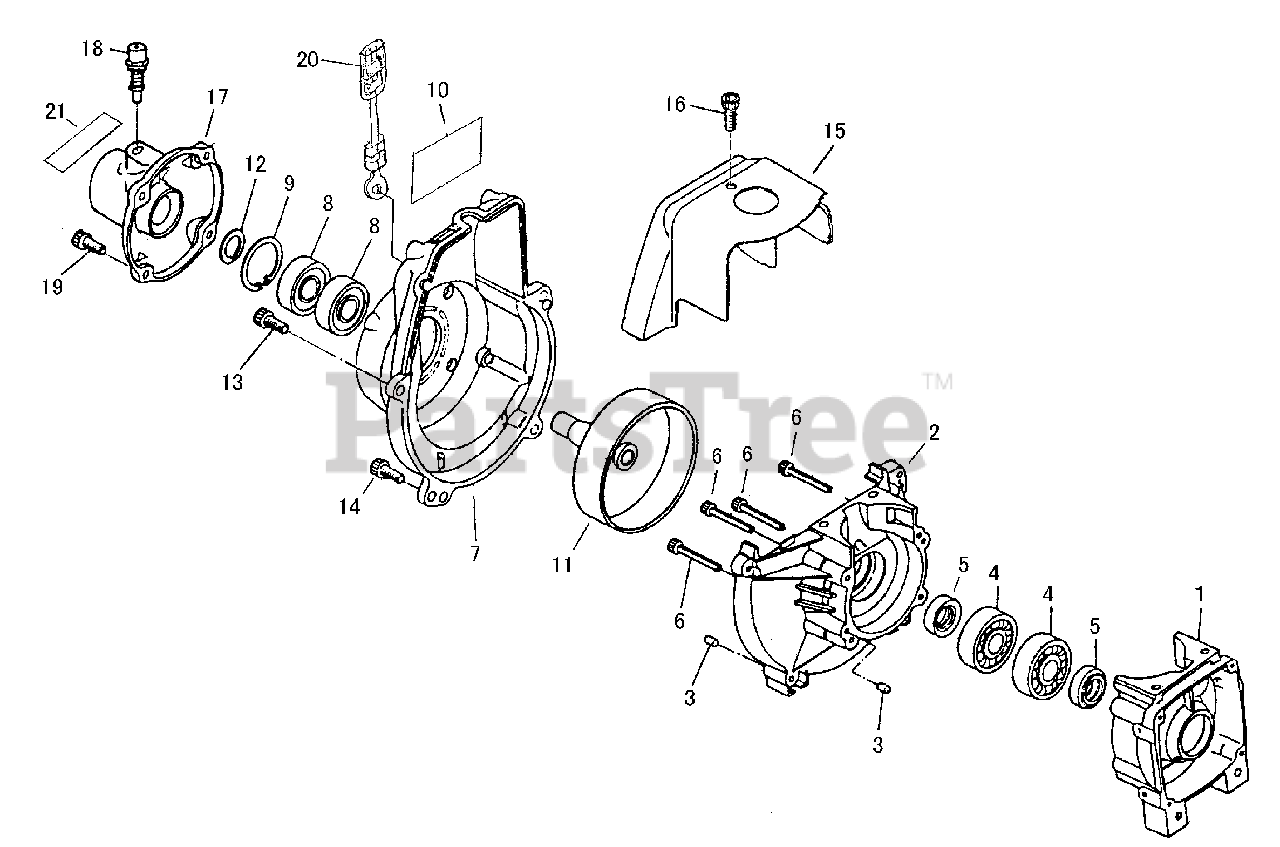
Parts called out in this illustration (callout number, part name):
1	CRANKCASE - REAR
2	CRANKCASE - FRONT
3	PIN - LOCATING
4	BEARING, BALL - 6202C3
5	SEAL, OIL
6	SCREW - 5X30
7	CASE, FAN
8	BEARING, BALL - 6002
9	RING, RETAINING - 32
10	LABEL - TRADE
11	DRUM, CLUTCH
12	RING, RETAINING
13	SCREW - 5X20
14	SCREW - 5X35
15	COVER, ENGINE
16	SCREW - 5X14
17	JOINT CASE
18	PIN ASSY
19	SCREW - 5X20
21	LABEL - TRADE
